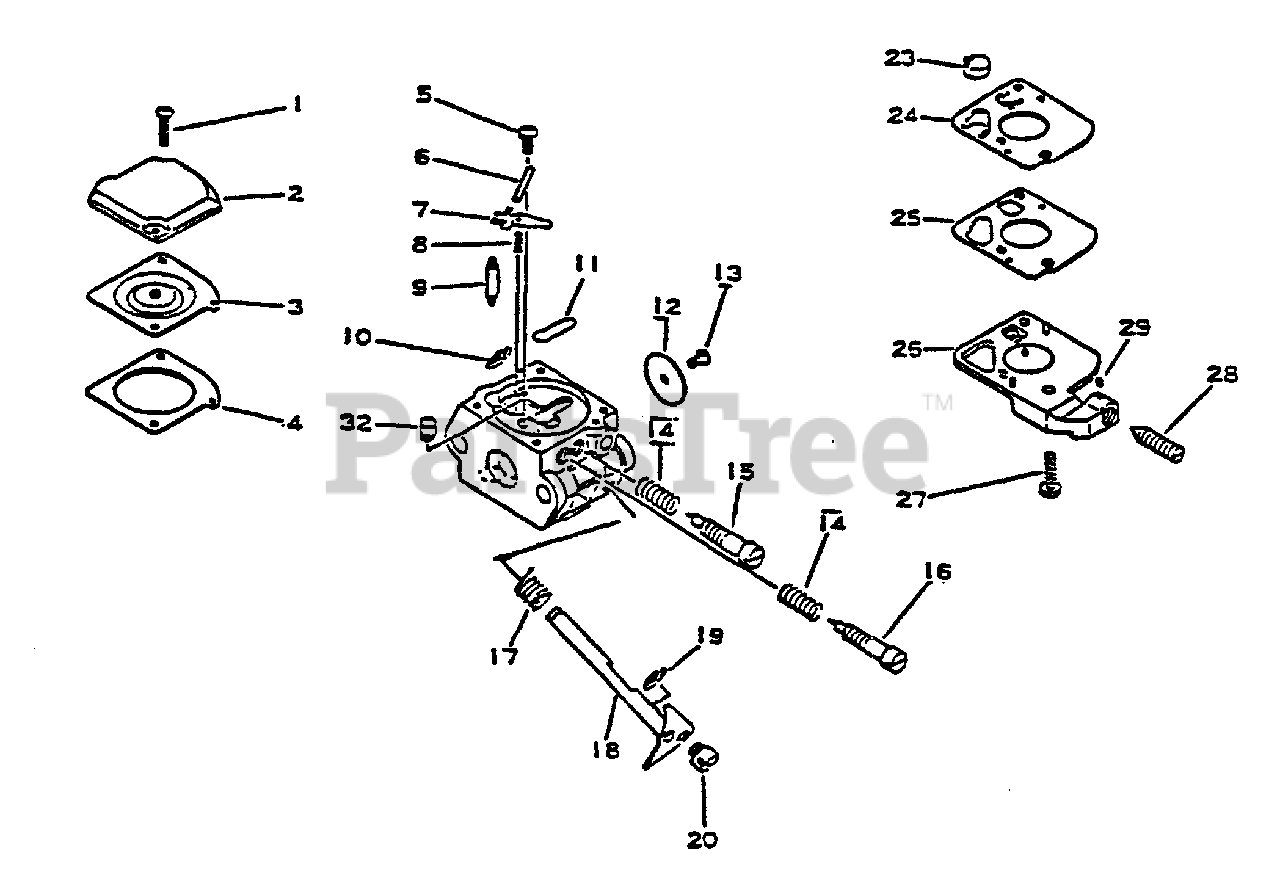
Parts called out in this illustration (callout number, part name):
2	Cover, Diaphragm
3	Diaphragm
4	Gasket, Diaphragm
6	Pin
7	Lever, Metering Cham
8	Spring, Coil
9	Valve, Needle
11	Plug, Welch
12	Valve, Throttle
14	Spring, Coil
15	Needle, High Speed
16	Needle, Idle
17	Spring, Thrt. Return
18	Shaft, Throttle
23	Strainer
24	Diaphragm, Fuel Pump
25	Gasket, Fuel Pump
26	Cover, Pump
28	Screw, Idle Adjust
29	Piece, Friction
32	Nozzle, Check Valve
